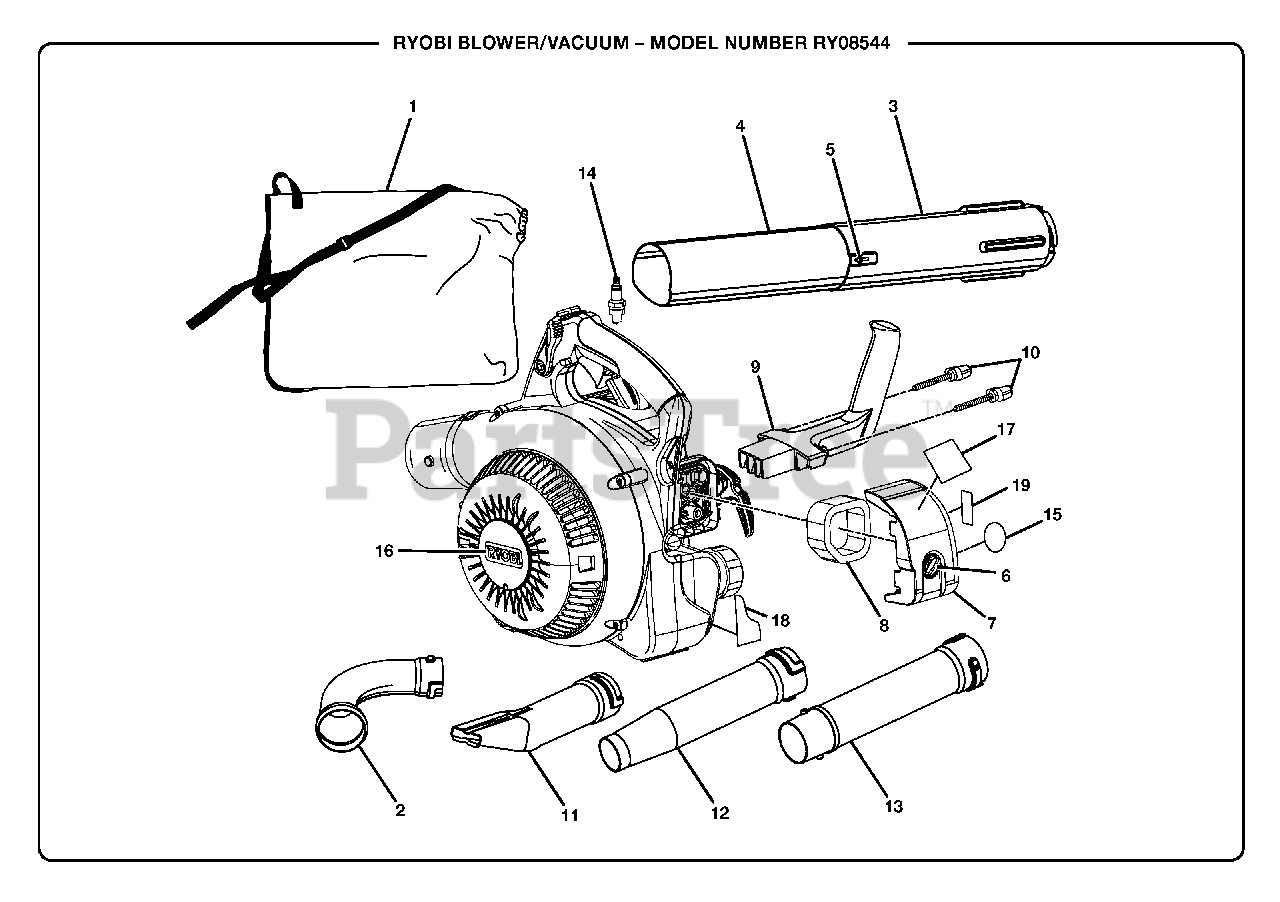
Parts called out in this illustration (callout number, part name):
1	Vacuum Bag w/Shoulder Strap
2	Vacuum Bag Adaptor
3	Upper Vacuum Tube
4	Lower Vacuum Tube
5	Vacuum Tube Screws
6	Air Filter Knob
7	Air Filter Cover
8	Air Filter
9	Vacuum Handle
10	Vacuum Handle Knobs
11	High Velocity Nozzle w/ Leaf Scraper
12	Sweeper Nozzle
13	Upper Blower Tube
14	Spark Plug (Champion RCJ6Y)
15	Zip Start Label
16	Vacuum Door Label
17	Starting Instructions Label
18	Warning Label
19	Starting Label
